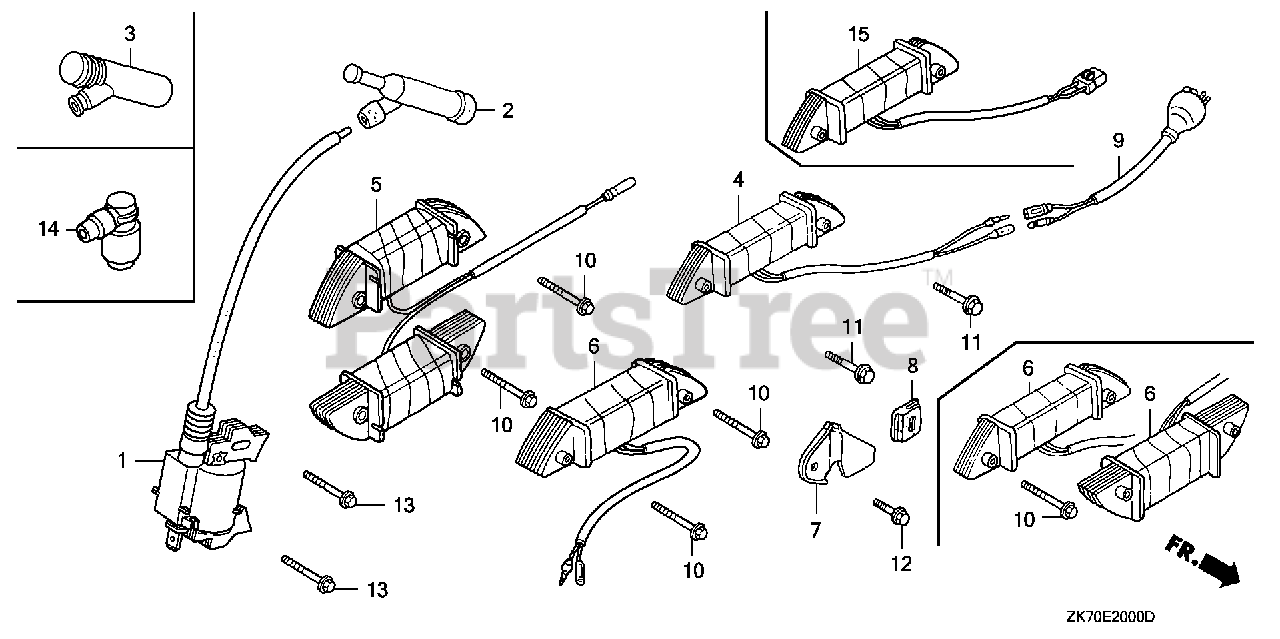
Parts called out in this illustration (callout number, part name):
1	COIL ASSY., IGNITION
2	CAP ASSY., NOISE SUPPRESSOR (NICHIWA Y-EZ RTFM256)
13	BOLT, FLANGE (6X25) (CT200)
